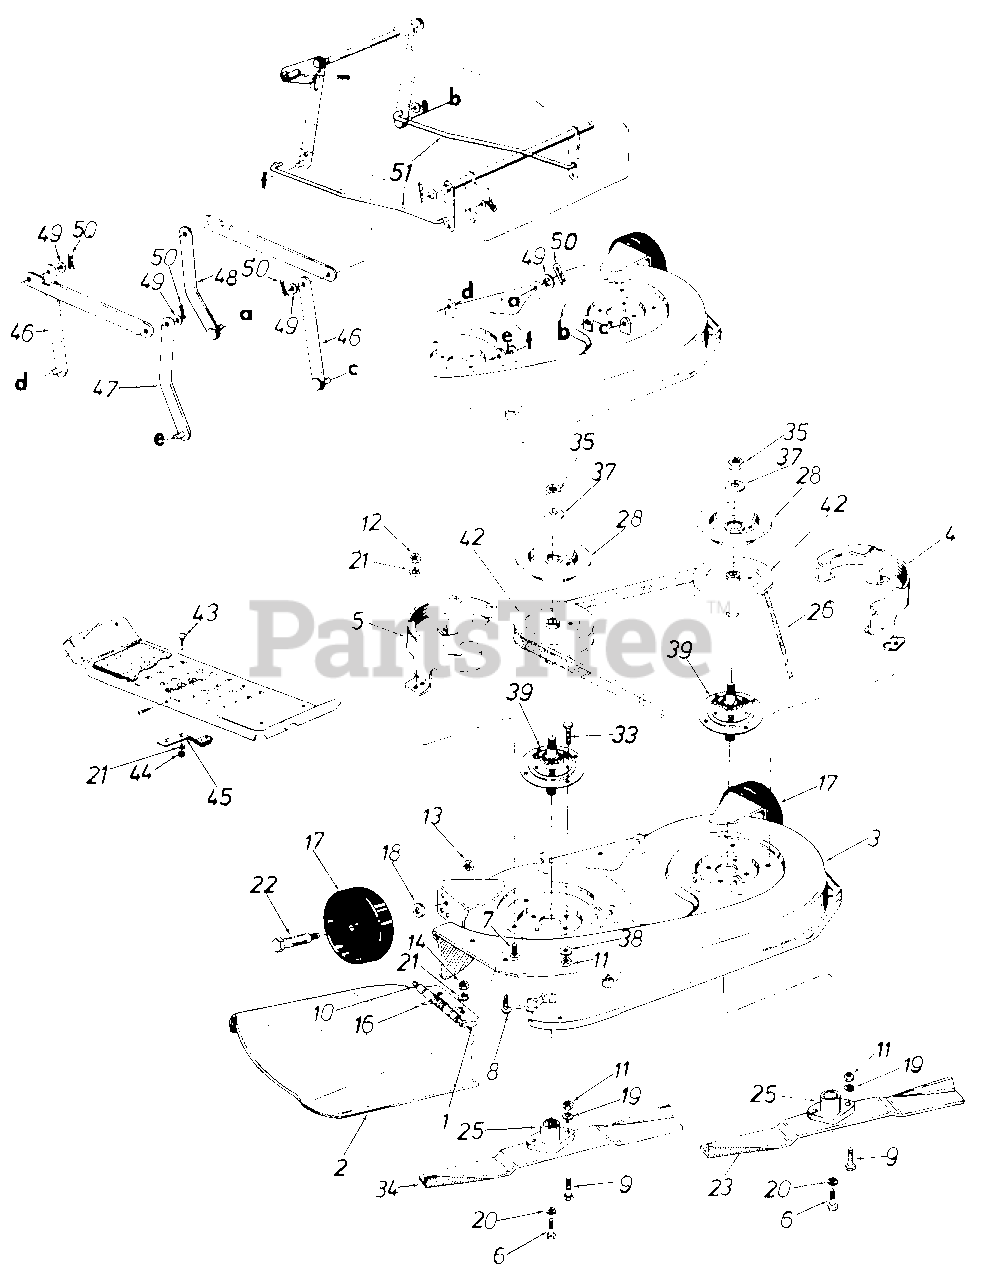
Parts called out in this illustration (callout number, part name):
1	Chute Bracket
2	Chute Deflector
3	38" Deep Deck Ass'y.
6	Hex Bolt 3/8-24 x 1.00"
7	Hex Bolt 1/4-28 x .62"
8	Truss Mach. Scr. 1/4-20 x .751"
9	Hex Bolt Special 5/16-24 x 1.0"
10	Hinge Pin
11	Hex Nut 5/16-24 Thd.
12	Hex Nut 1/4-28 Thd.
13	Hex Top L-Nut 3/8-16 Thd.
14	Hex Jam Nut 1/4-20 Thd.
16	Torsion Spring
17	Deck Wheel-5"
18	Bell-Wash. .40" I.D. x .88" O.D.
19	L-Wash. 5/16" I.D.
20	L-Wash. 318" I.D.-H.D.
21	L-Wash. 1/4" l.D.
22	Shld. Bolt .498" Dia. x 1.53"
23	High-Lift Blade-L.H.
25	Blade Adapter
26	5L V-Belt
28	Brake Disc
33	Rib Neck Bolt 5/16-24 x 1.05" Lg.
34	High-Lift Blade-R.H.
35	Hex Jam Nut 5/8-18 Thd.
37	L-Wash. 5/8" I.D.
38	L-Wash. 5/16" I.D.
39	Blade Spindle Ass'y. Comp.
42	5" Dia. Pulley
43	Carr. Bolt 1/4-20 x .62"
44	Hex Nut 1/4-20 Thd.
45	Blade Brake Ass y.
46	Link Deck Hanger Ass'y.
47	Link Deck Hanger Ass'y.
50	Inter. Cotter Pin .50" Dia.
51	Stabilizer Rod
